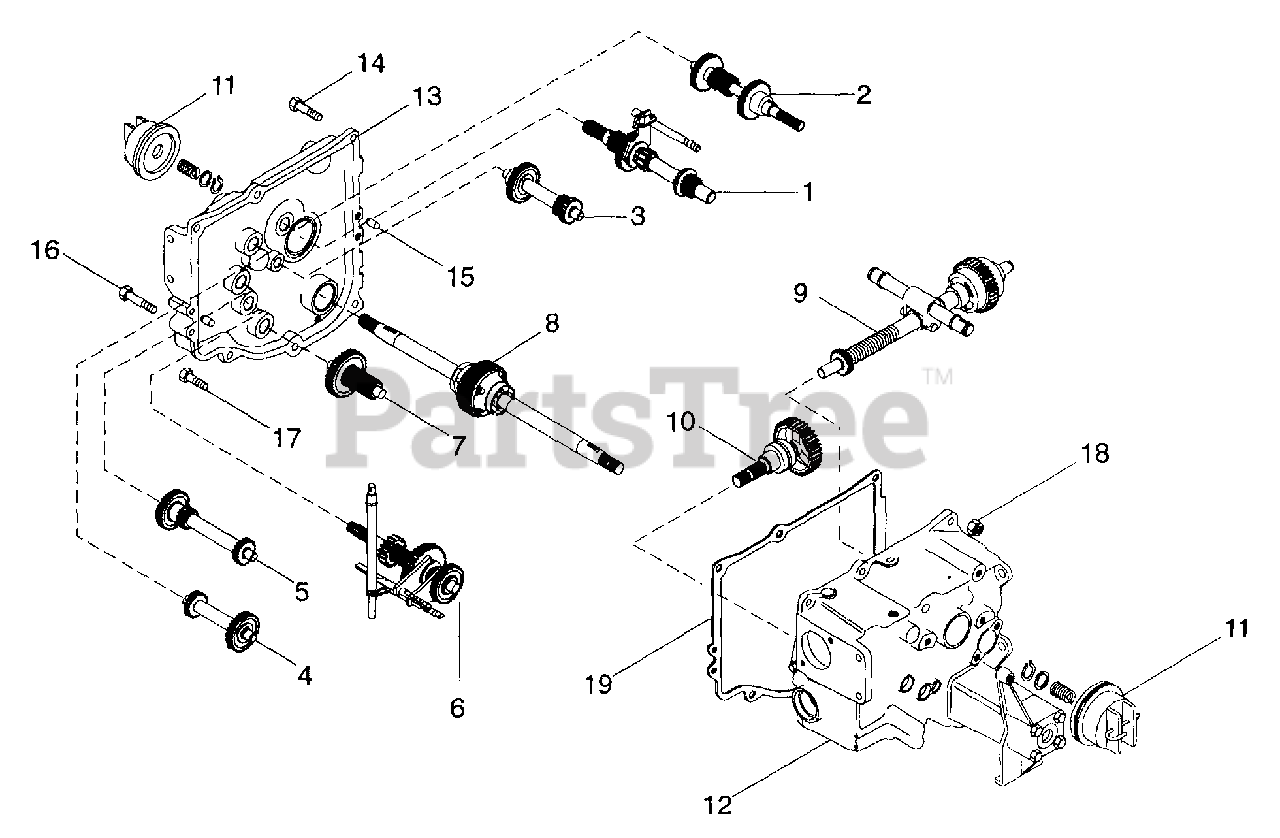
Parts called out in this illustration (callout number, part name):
14	Bolt-Hex .38-16 x 2.00 Grade 5
15	Pin-Dowel .38 x .625
16	Bolt-Hex .38-16 x 2.25 Grade 5
17	Bolt-Hex .38-16 x 1.50 Grade 5
18	Nut-Locking-Nylon .375-16 Grade 2
19	Gasket, Transmission Cover
